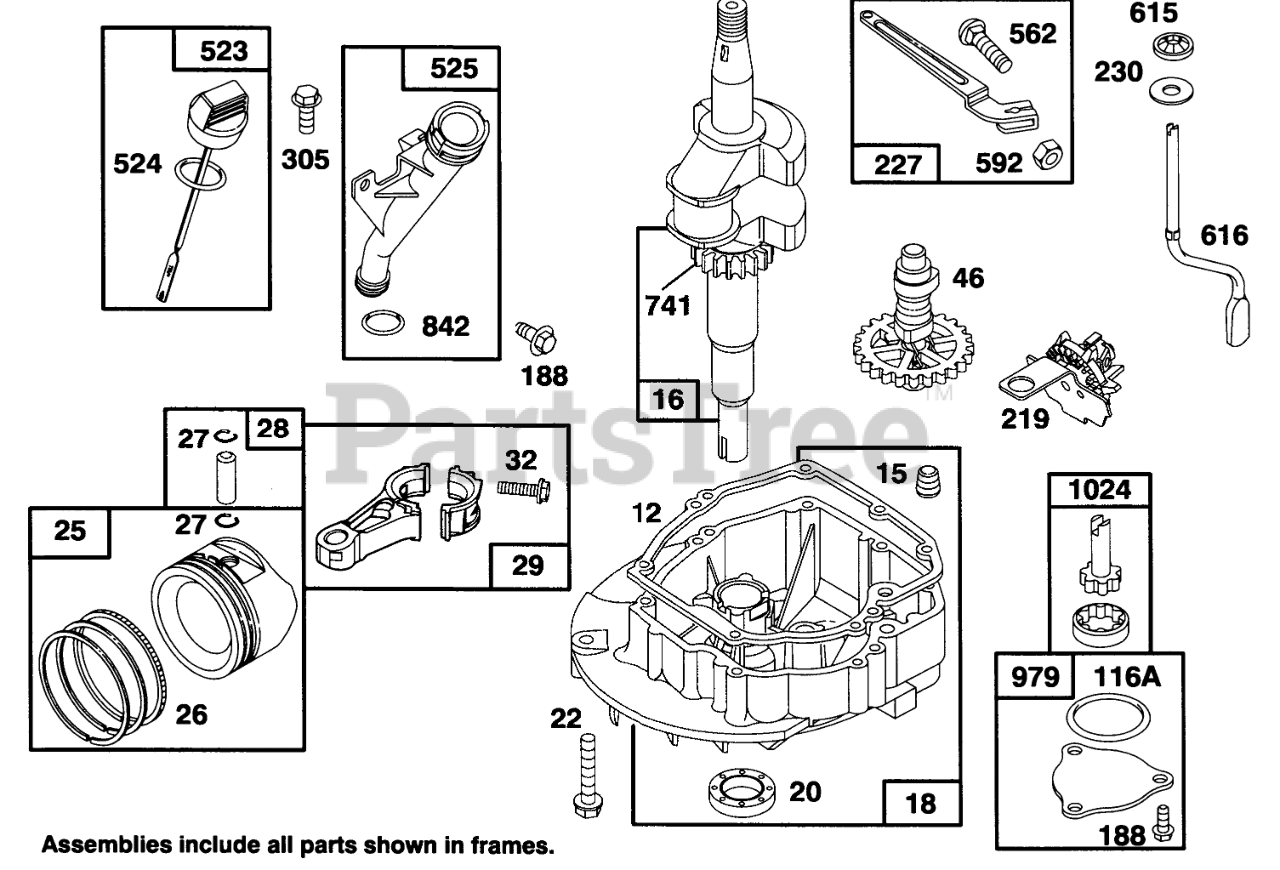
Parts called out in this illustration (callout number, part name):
12	ENGINE BASE GASKET
15	PIPE PLUG
16	Crankshaft
18	ENGINE SUMP
20	SEAL-OIL
22	SCREW - ENGINE BASE
25	STD PISTON ASSEMBLY
26	STD RING SET
27	PISTON PIN LOCK
28	PIN ASM - PISTON
29	CONNECTING ROD
32	SCREW - CONNECTING ROD
46	CAM GEAR
116A	O RING SEAL
188	Screw-Cap
219	GOVERNOR/OIL SLINGER
227	GOVERNOR LEVER ASSEMBLY
230	WASHER
305	SCREW - HEX HEAD
523	DIPSTICK-OIL
524	O-RING
525	OIL FILLER TUBE
562	GOVERNOR LEVER BOLT
592	HEX NUT
615	FASTENER
616	GOVERNOR CRANK
741	TIMING GEAR
842	O-RING
979	OIL PUMP COVER
1024	OIL PUMP
